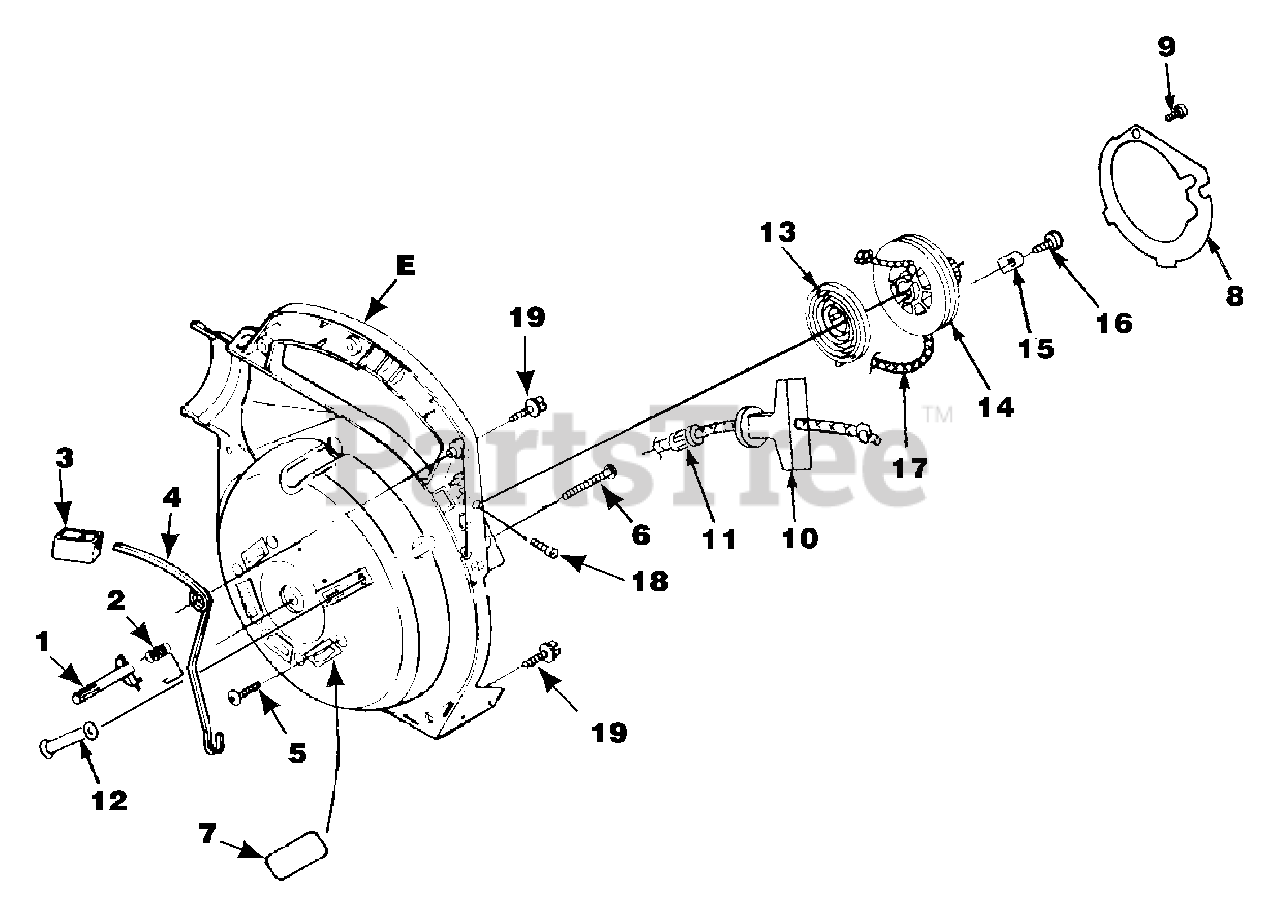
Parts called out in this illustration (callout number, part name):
1	LATCH-Throttle
2	SPRING-Throttle Latch
3	TRIGGER-Throttle
4	LEVER-Throttle
5	SCREW-Thread Form. (10-24 X 3/4")
6	SCREW-Thread Form. (#10 X 1 5/8")
7	KIT-Sealing
8	PLATE-Rotor
9	SCREW-Thread Form. (#6 X 1 3/8")
10	GRIP-Starter
11	BUSHING-Starter
12	BUSHING-Starter Rope
13	SPRING & CONTAINER
14	PULLEY-Starter
15	BRACKET-Retaining
16	SCREW-Thread Form. (#10 X 1/2")
17	ROPE-Starter
18	SCREW-Phil. Hd. (8-32 X 5/8")
19	SCREW-Thread Form. (10-24 X 3/4")
E	VOLUTE HOUSING & STARTER
